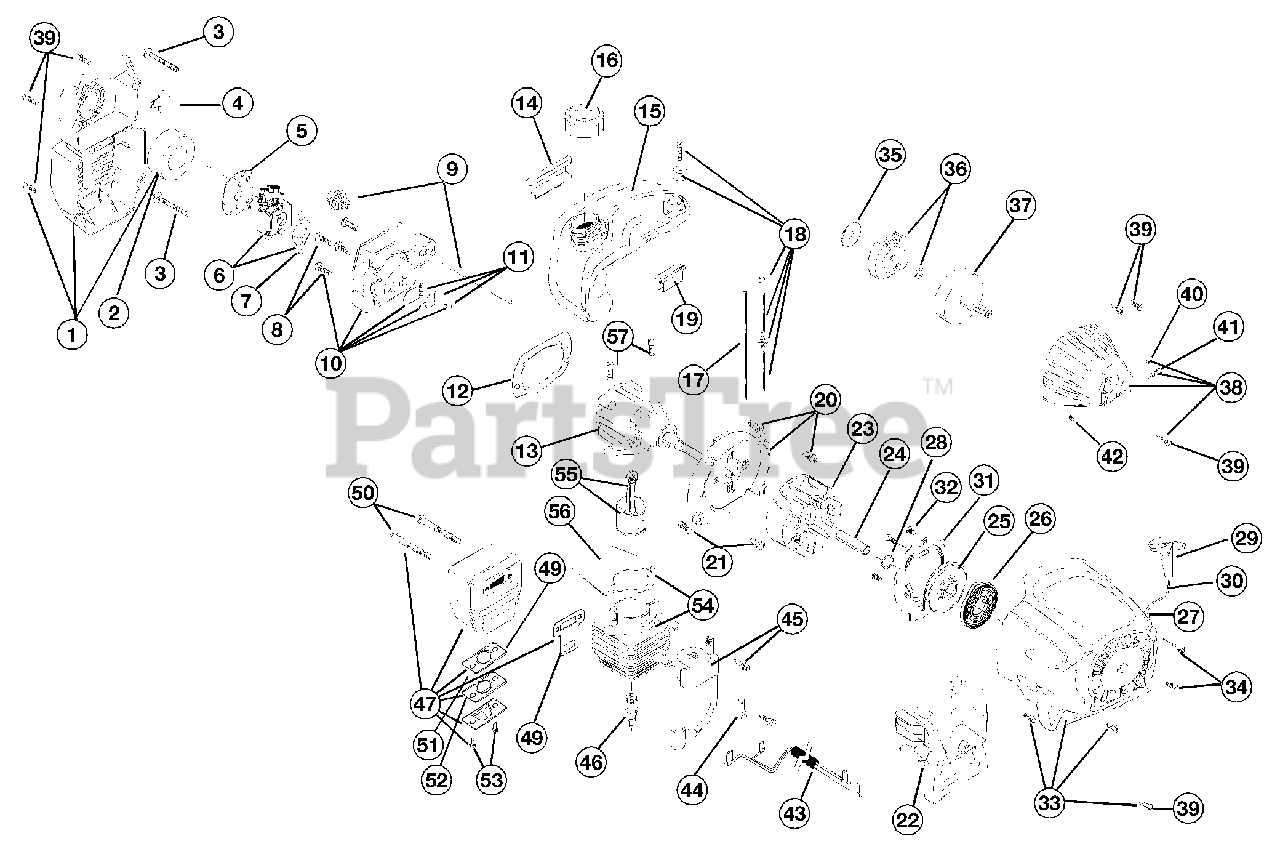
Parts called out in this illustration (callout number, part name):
1	Air Cleaner/Muffler Cover Assembly
2	Air Cleaner Filter
3	Carburetor Mounting Screw Assembly
4	Choke Extension
5	Choke Plate
6	Carburetor Assembly
7	Carburetor Gasket
8	Carb Mount Screw
9	Primer and Hose Assembly
10	Carb Mount Assembly
11	Reed Assembly
12	Carburetor Mount Gasket
13	Crank Case Service Assembly
14	Rear Mounting Pad
15	Fuel Tank Assembly
16	Fuel Cap Assembly
17	Fuel Return Line
18	Fuel Line Assembly
19	Front Mounting Pad
20	Shroud Assembly
21	Shroud Screw
22	Shroud Extension and Stand
23	Flywheel Assembly
25	Recoil Pulley Assembly
26	Recoil Spring
27	Rope Guide
28	Pulley Retainer
29	Pull Handle
31	Pressure Plate Assembly
32	Plate Screw
33	Starter Housing Assembly
34	Housing Screw
35	Clutch Washer
36	Clutch Rotor Assembly
37	Clutch Drum Assembly
38	Clutch Cover Assembly
39	Cover Screw
40	Anti-Rotation Screw
41	Clamping Screw
42	Clamping Nut
43	Wire Leads and Sleeve
44	Ground Tab
45	Module Assembly
47	Muffler Assembly
48	Spark Arrestor Screen
49	Exhaust Gasket
50	Muffler Mounting Bolt
51	Spark Arrestor Plate
52	Spark Arrestor Hood
53	Spark Arrestor Screw
54	Cylinder Assembly
55	Piston and Rod Assembly
56	Cylinder Gasket
57	Cylinder Bolt
